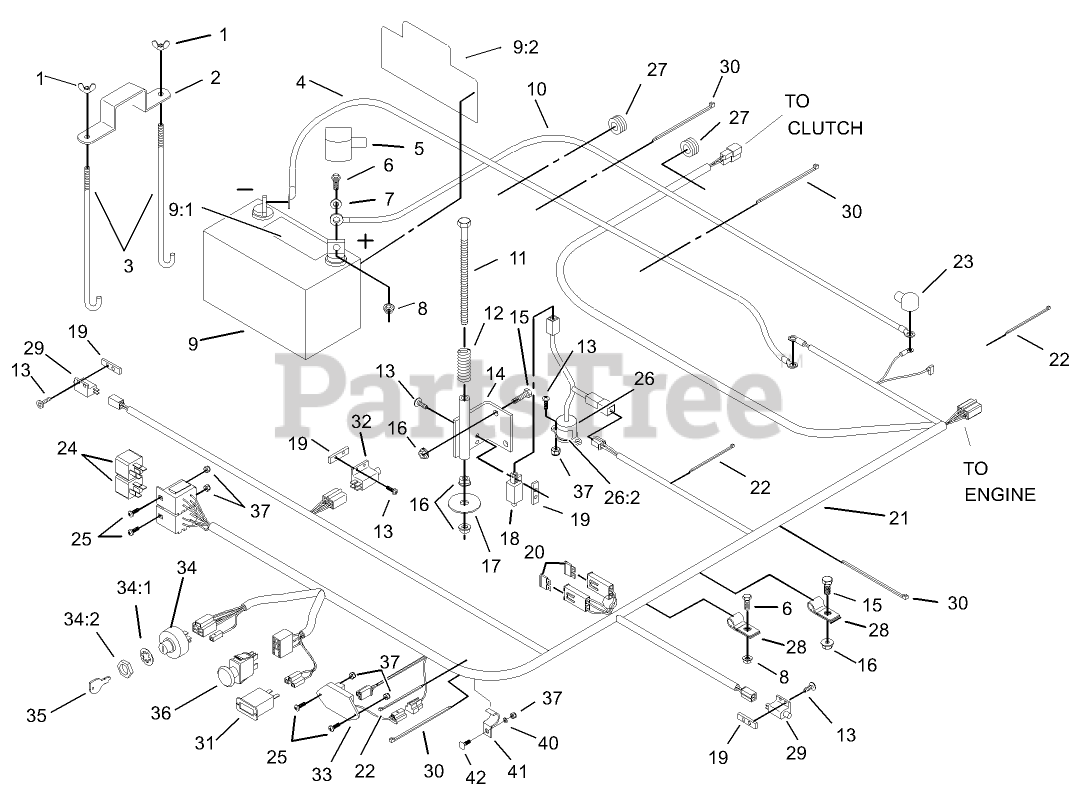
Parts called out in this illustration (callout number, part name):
1	WINGNUT
2	STRAP-HOLDDOWN
3	BOLT-HOLDDOWN
4	WIRE-GROUND
5	INSULATOR-BATTERY
6	SCREW-HH
7	WASHER-FLAT
8	NUT-HF
9	BATTERY
9:1	Decal-Battery
9:2	Decal-Battery
10	WIRE-STARTER
11	SCREW-HH
12	SPRING-SWITCH, SEAT
13	SCREW-PPH
14	BRACKET-SWITCH, SEAT
15	SCREW-HH
16	NUT-HF
17	WASHER
18	SWITCH-CLOSED, NORMALLY
19	PLATE-TAPPED
20	FUSE-BLADE TYPE, 20 AMP
21	HARNESS-WIRE
22	TIE-CABLE
23	INSULATOR-SOLENOID
25	BOLT-CARR
26	TILT SWITCH ASM
26:2	DECAL-SWITCH, MERCURY
27	GROMMET
28	CLIP-LOOM
29	SWITCH-OPEN, NORMALLY
30	TIE-PLASTIC
31	METER-HOUR
32	SWITCH
33	MODULE-DELAY, SEAT
34	Key Switch ASM
34:1	WASHER-TOOTH, INTERNAL
34:2	NUT-HH
35	KEY-IGNITION
36	SWITCH-DELTA
37	NUT-LOCK, NI
40	WASHER-FLAT
41	CLIP-HALF, LOOM
42	BOLT-CARR
